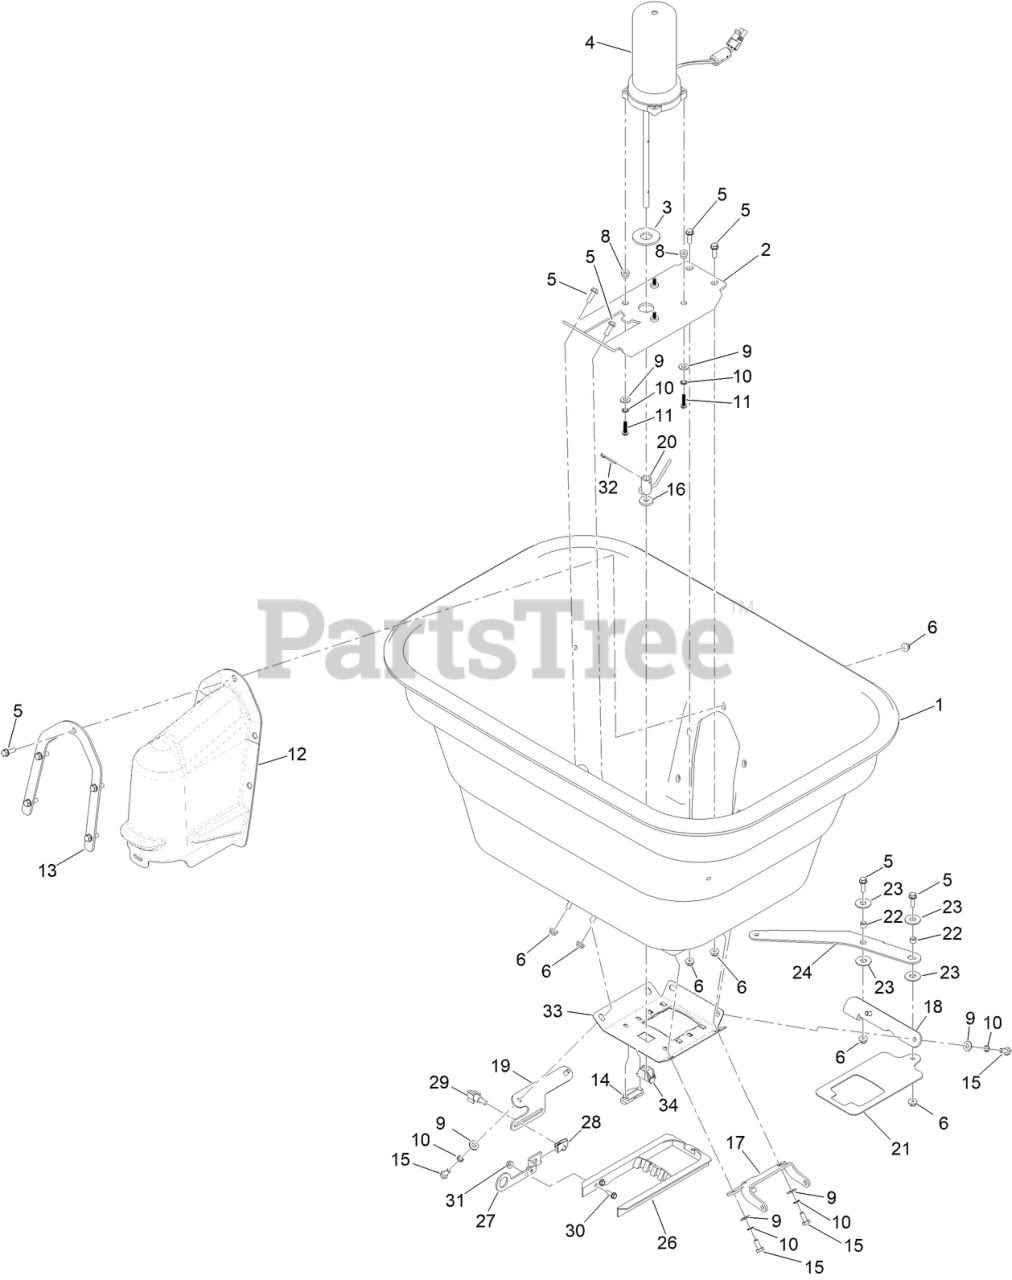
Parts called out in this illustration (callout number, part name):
1	HOPPER-SPREADER, 175 LB
2	MOUNT-MOTOR
3	SPACER
4	MOTOR-SPREADER
5	SCREW-HWH
6	NUT-HF
8	SPACER-FLANGED
9	WASHER-FLAT
10	WASHER-LOCK, INT
11	SCREW-SHWH
12	COVER-MOTOR
13	SUPPORT-COVER
14	GUIDE-RATE, GATE
15	SCREW-HH
16	WASHER-FELT
17	MOUNT-DEFLECTOR
18	MOUNT-GATE, PIVOT
19	MOUNT-GATE, PIVOT
20	WELD-AGITATOR
21	GATE-SPREADER SEED
22	SPACER
23	WASHER
24	ARM-ENGAGEMENT
26	DIFFUSER-ACCESSORY
27	BRACKET-ACCUWAY, SLIDE
29	KNOB-STAR, THREE
31	NUT-LOCK, FLANGE
32	PIN-COTTER
33	BOTTOM-MULCH
34	HOPPER BOTTOM BEARING
